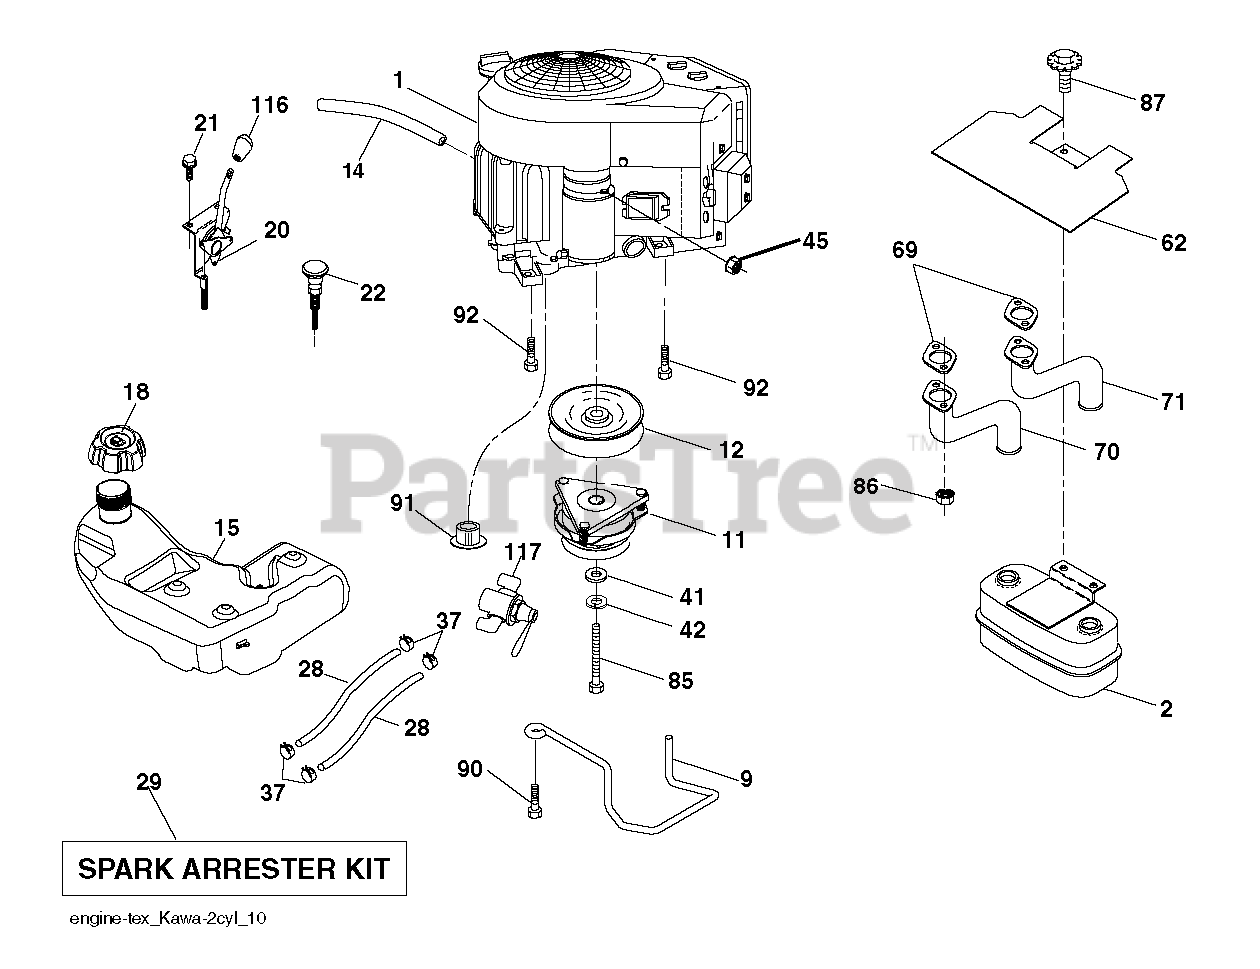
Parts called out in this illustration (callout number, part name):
2	MUFFLER.TWIN.CYL.LOW.TONE
9	KEEPER.BELT.ENGINE.4.2
11	CLUTCH.ELECTRIC.LT.48"*
12	PULLEY.ENGINE.TUFFTORQ
14	TUBE, DRAIN OIL ASM.
15	RP_TANK.ASSY.4.GAL.2.PORT.EPA
18	CAP.ASM.FL.RITCH.3"E10.SYM.498
20	CONTROL.THROTTLE.PRO.
21	SCREW.#10 X 0.750.BOS
22	CONTROL.CHOKE.ERGO.PUSH-IN.BLA
28	LINE.FUEL.64"REAR.EMIS
29	KIT.SPARK ARRESTOR 794945 B&S
37	HOSE CLAMP
42	LOCKWASHER
45	NUT
62	SHIELD.HEAT.MUFFLER
70	TUBE.EXHAUST.LH.FR961/FR730
71	TUBE.EXHAUST.RH.FR961/FR730
85	BOLT HEX 7/16-20X4-1/4"
86	NUT.HEX.FLANGE.TOPLOCK
87	BOLT 5/1618UNC X 3/4 W/ SEMS
90	SCREW 3/8-16X1
91	BUSHING.1.375OD
92	SCREW 3/8-16X1
116	KNOB - SHIFT
117	VALVE FUEL RESERVE
